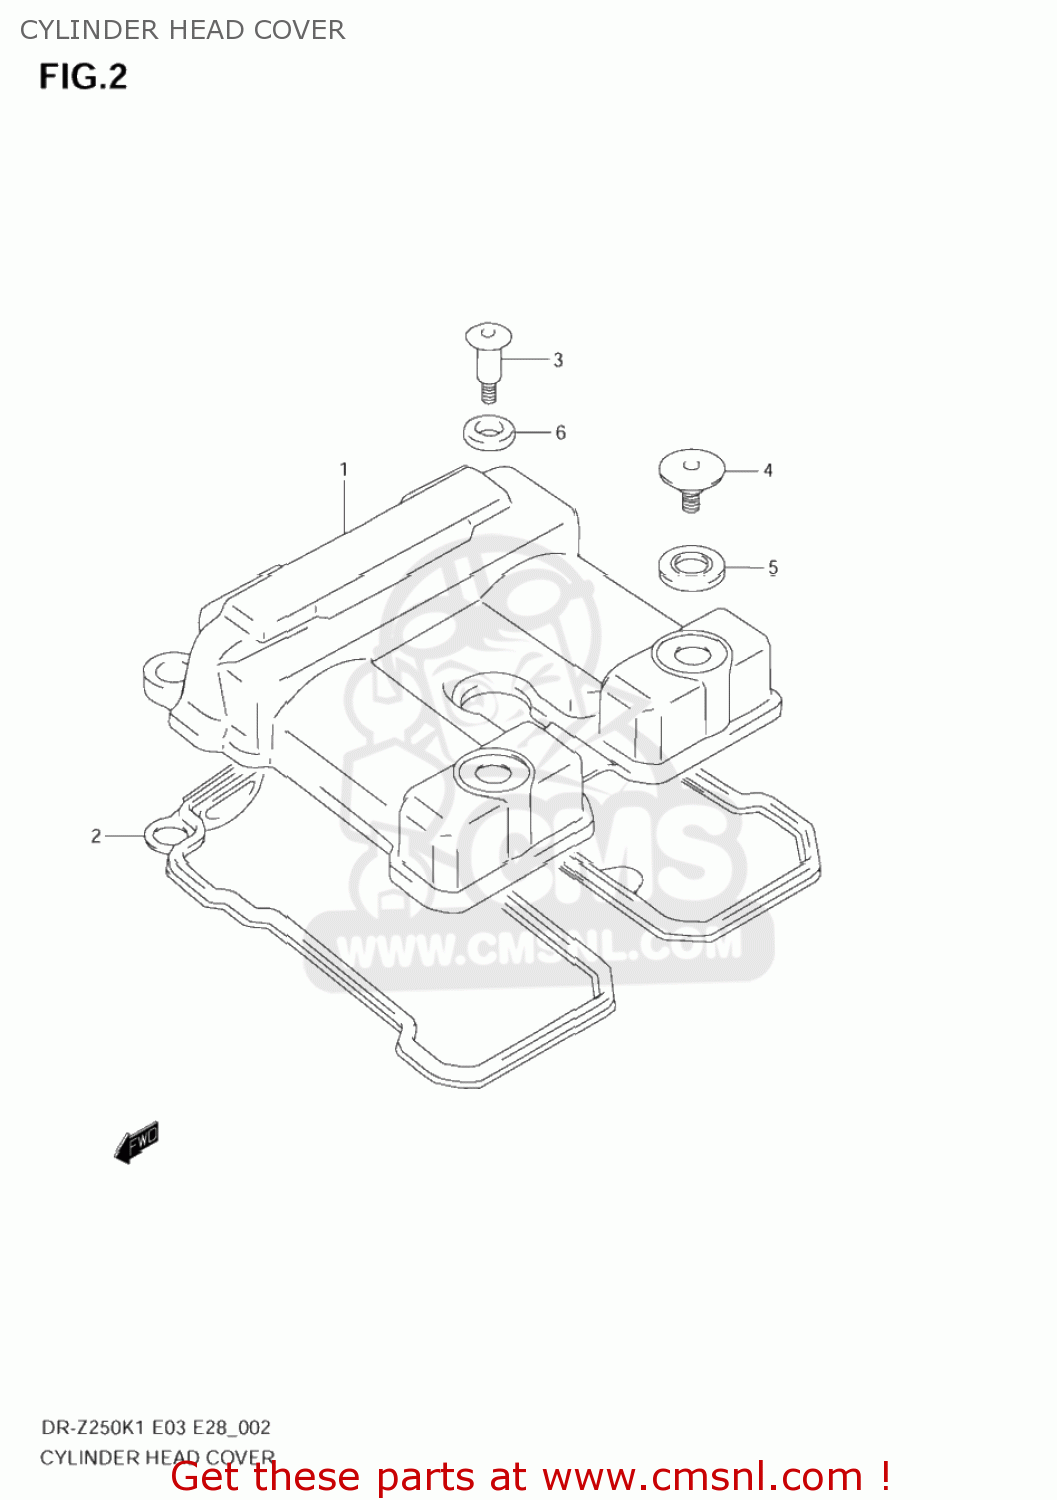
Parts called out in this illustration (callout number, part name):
1	COVER,CYLINDER HEAD
2	GASKET,CYL HEAD COVER
3	BOLT(7X31)
4	BOLT(7X18.5)
5	WASHER,HEAD COVER
6	CUSHION,HEAD COVER BOLT
